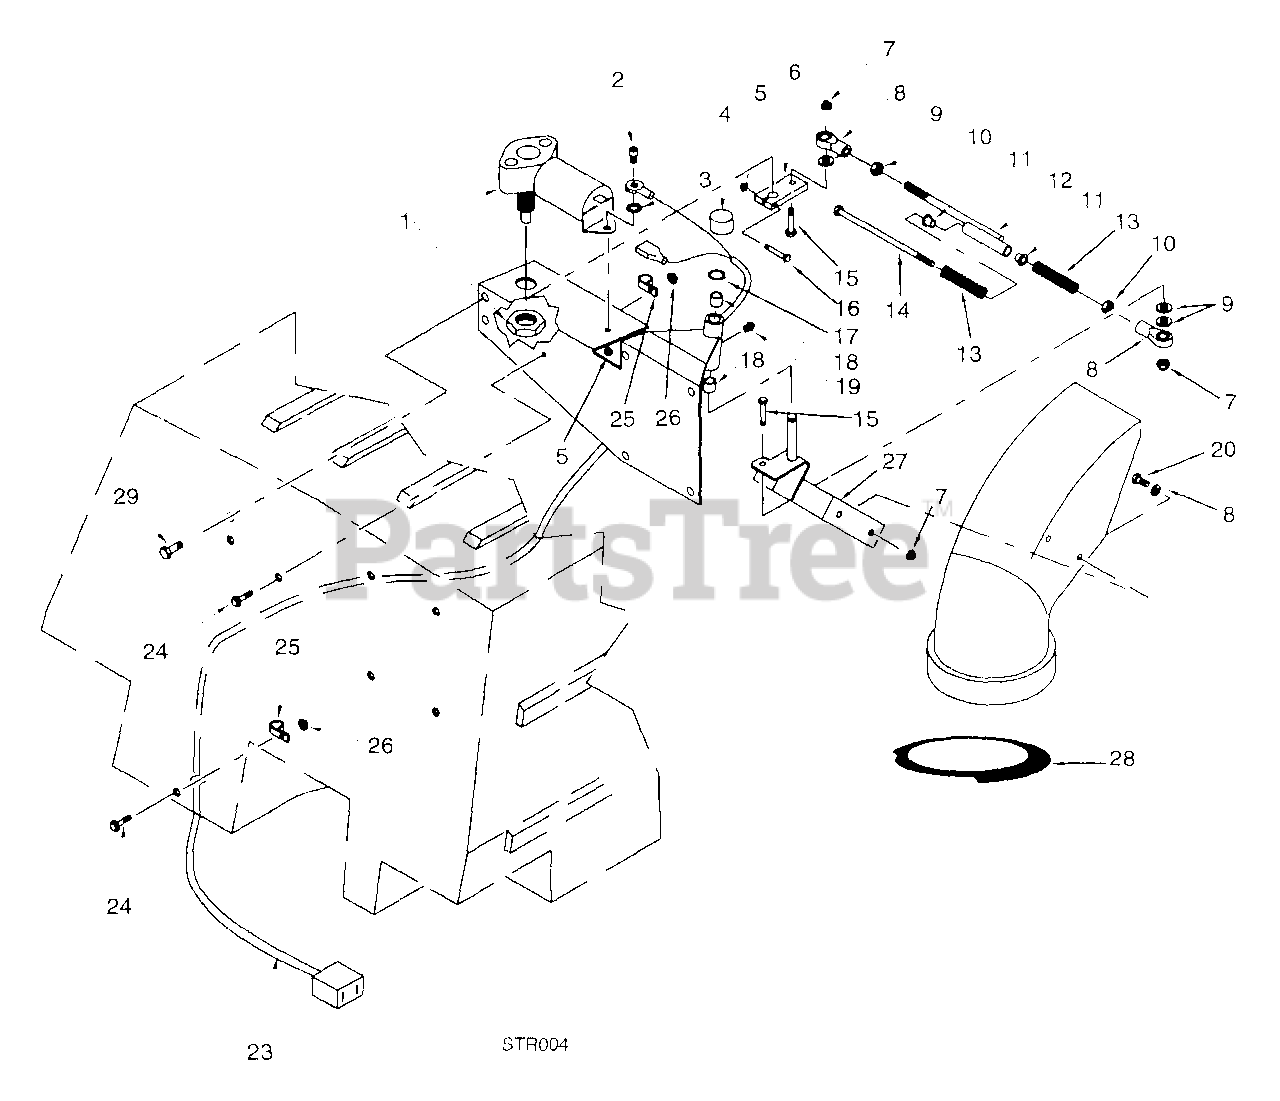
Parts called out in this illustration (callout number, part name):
1	Motor, Actuator
2	Capscrew, Sockt Head, #10-32 x 1/2"
3	Washer, External
4	Cap, Plastic
5	Hex Locknut, Elastic Stop, #10-32
6	Lever, Actuator
7	Hex Locknut, Elastic Stop, 5/16-18
8	Rod End, 5/16-18 R.H. Thread
9	Flatwasher, 5/16 (.375 x .875.x .083)
10	Hex Nut, 5/16-18
11	Bushing, Nylon
12	Connecting Rod
13	Spring, Connecting Rod
14	Bolt, Hex Head, 5/16-18 x 7.00"
15	Bolt, Hex Head, 5/16-18 x 1-1/4"
16	Capscrew, Socket Head, #10-32 x 1-1/2"
17	Retainer Ring
18	Bushing, Oilite, .502 ID
19	Grease Fitting
20	Bolt, Hex Head, 5/16-18 x 3/4"
23	Wire Harness, Hopper
24	Serr. Fl. Hex Head CPSCR, 1/4-20 x 3/4"
25	Clamp, Cable, 1/2"
26	Serr. Fl. Hex Nut, 1/4-20
27	Pivot, Elbow
28	Seal, Hopper Elbow
29	Body Bolt, 5/16-18 x .81"
